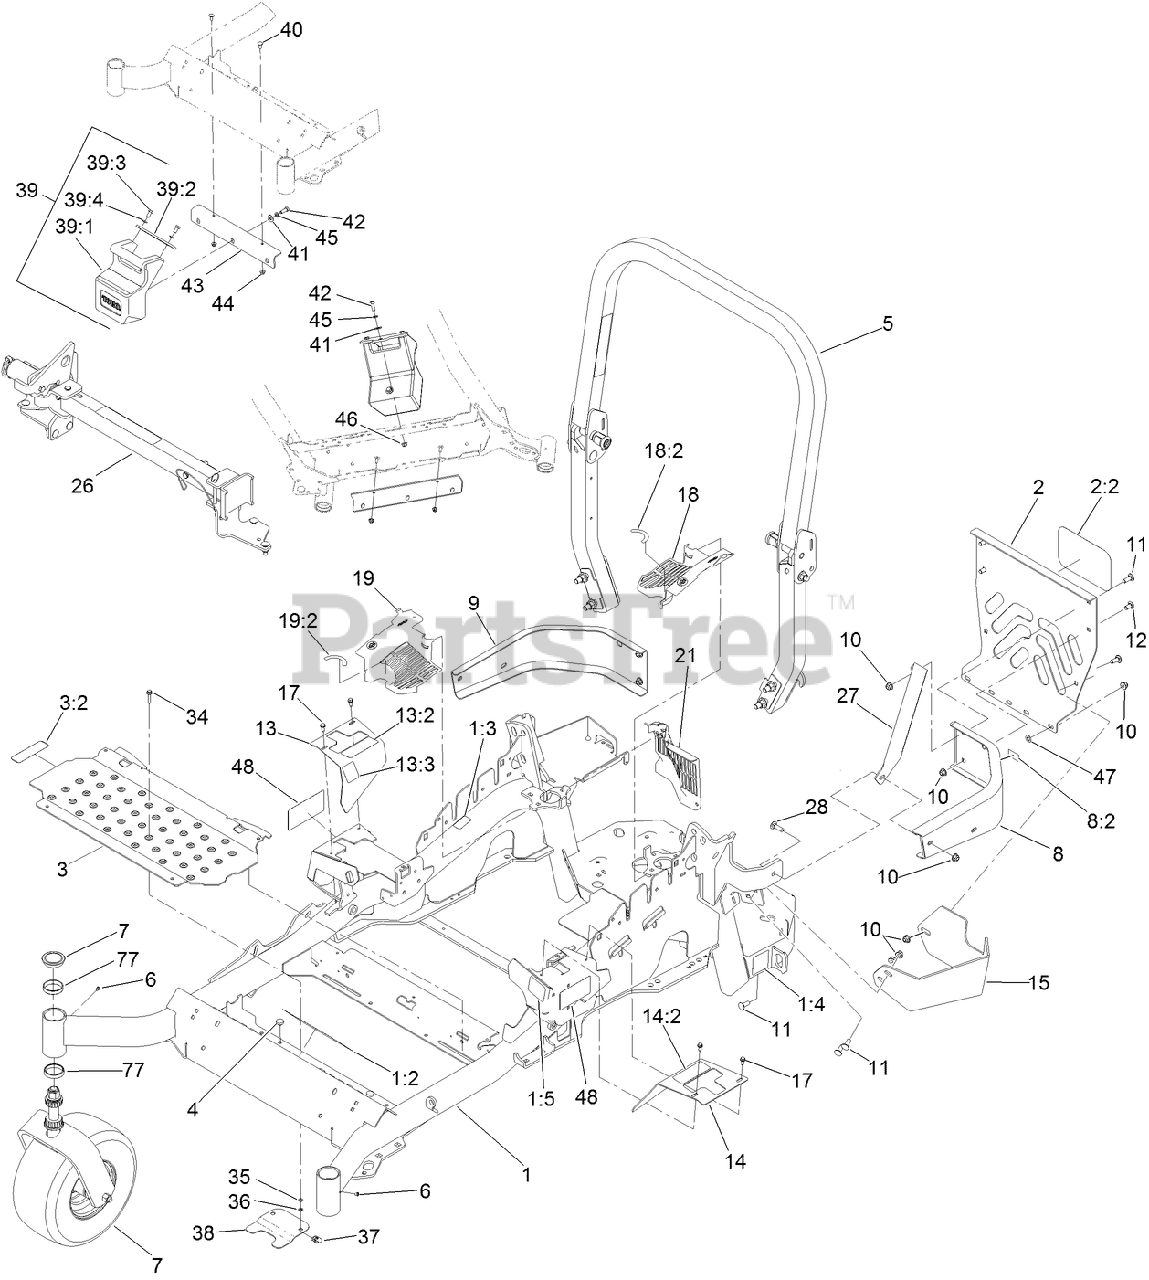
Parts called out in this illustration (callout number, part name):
1	MAIN FRAME ASM
1:2	DECAL-DANGER
1:3	DECAL-WARNING
1:4	DECAL-HAZARD, PINCHED FINGER
1:5	DECAL-FUEL FILL, CE
2	REAR GUARD ASM
2:2	DECAL
3	FLOORPAN ASM
3:2	DECAL-MISSING, COVER
4	BUMPER
5	ROPS ASM
7	FRONT CASTER ASM
8	LH REAR BUMPER ASM
8:2	DECAL-WARNING
9	BUMPER-RH
10	NUT-HF, NI
11	SCREW-CARR
12	SCREW-CARR
13	RH MOTION CONTROL COVER ASM
13:2	DECAL-CONTROL, MOTION
13:3	DECAL-PARK BRAKE, CE
14	LH MOTION CONTROL COVER ASM
14:2	DECAL-CONTROL, MOTION
15	GUARD-MUFFLER
17	SCREW-HWH
18	LH HYDRO GUARD ASM
18:2	DECAL-HYDRO OIL
19	RH HYDRO GUARD ASM
19:2	DECAL-HYDRO OIL
21	GUARD-HYDRO, REAR (RH)
26	Z STAND ASM
28	BOLT-CARR
34	SCREW-HHF
35	WASHER-FLAT
36	NUT-RETAINER
38	ADAPTER-CAPTIVE
39	WEIGHT ASM
39:1	WEIGHT-43 LB
39:2	TAB-SUPPORT, WEIGHT
39:3	SCREW-HH
39:4	WASHER-LOCK
40	SCREW-CARR
41	WASHER-FLAT
42	SCREW-HH
43	BRACKET-MOUNT, WEIGHT
44	NUT-HF, NI
45	WASHER-LOCK
46	NUT-HF, NI
47	NUT-PUSH
77	CUP-BEARING
